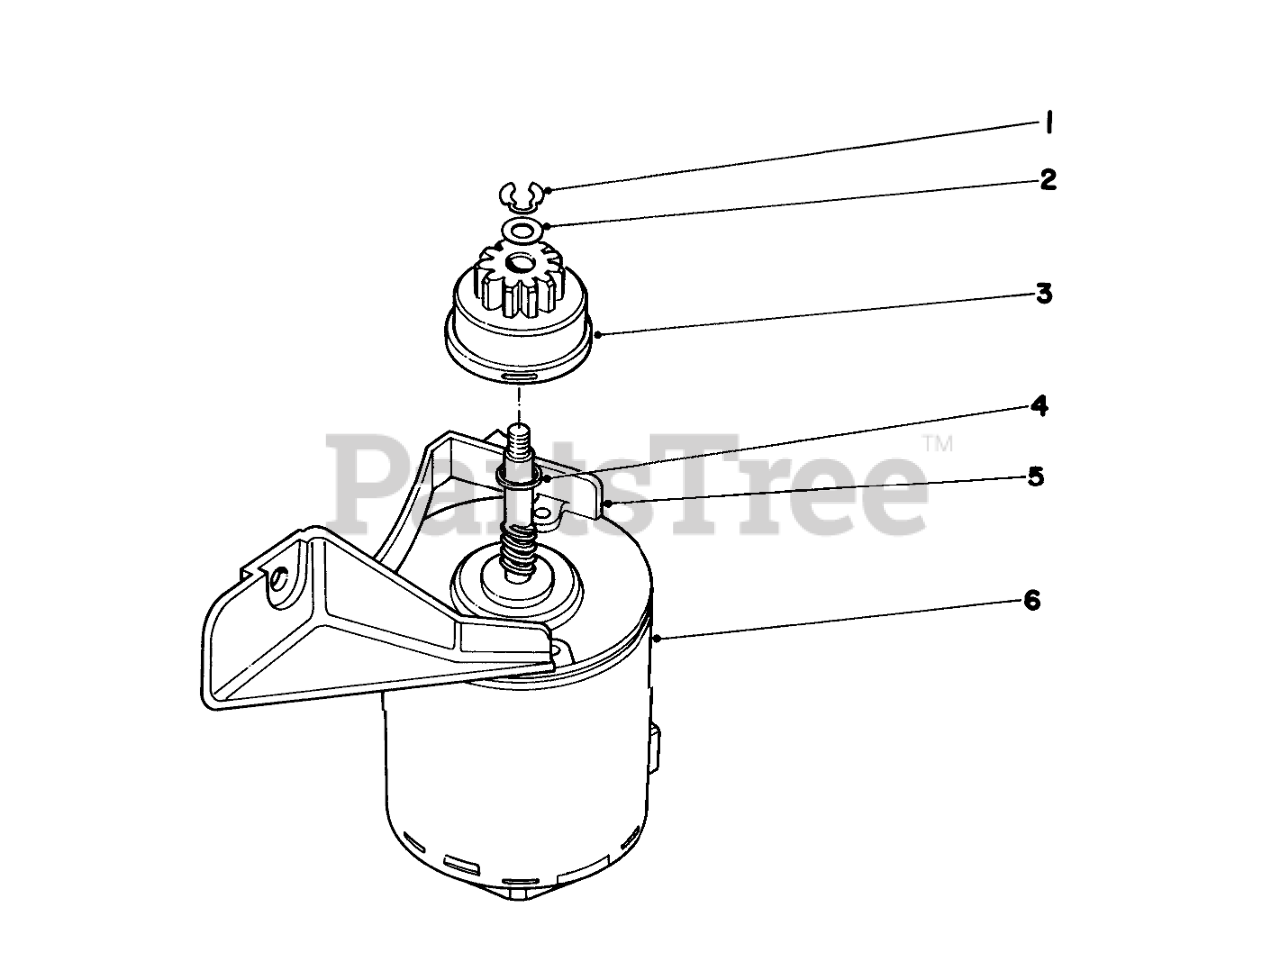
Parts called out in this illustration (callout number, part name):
1	RING-RETAINING
2	WASHER
3	PINION ASM
4	Spacer
5	Mounting Bracket
6	Starter Motor
